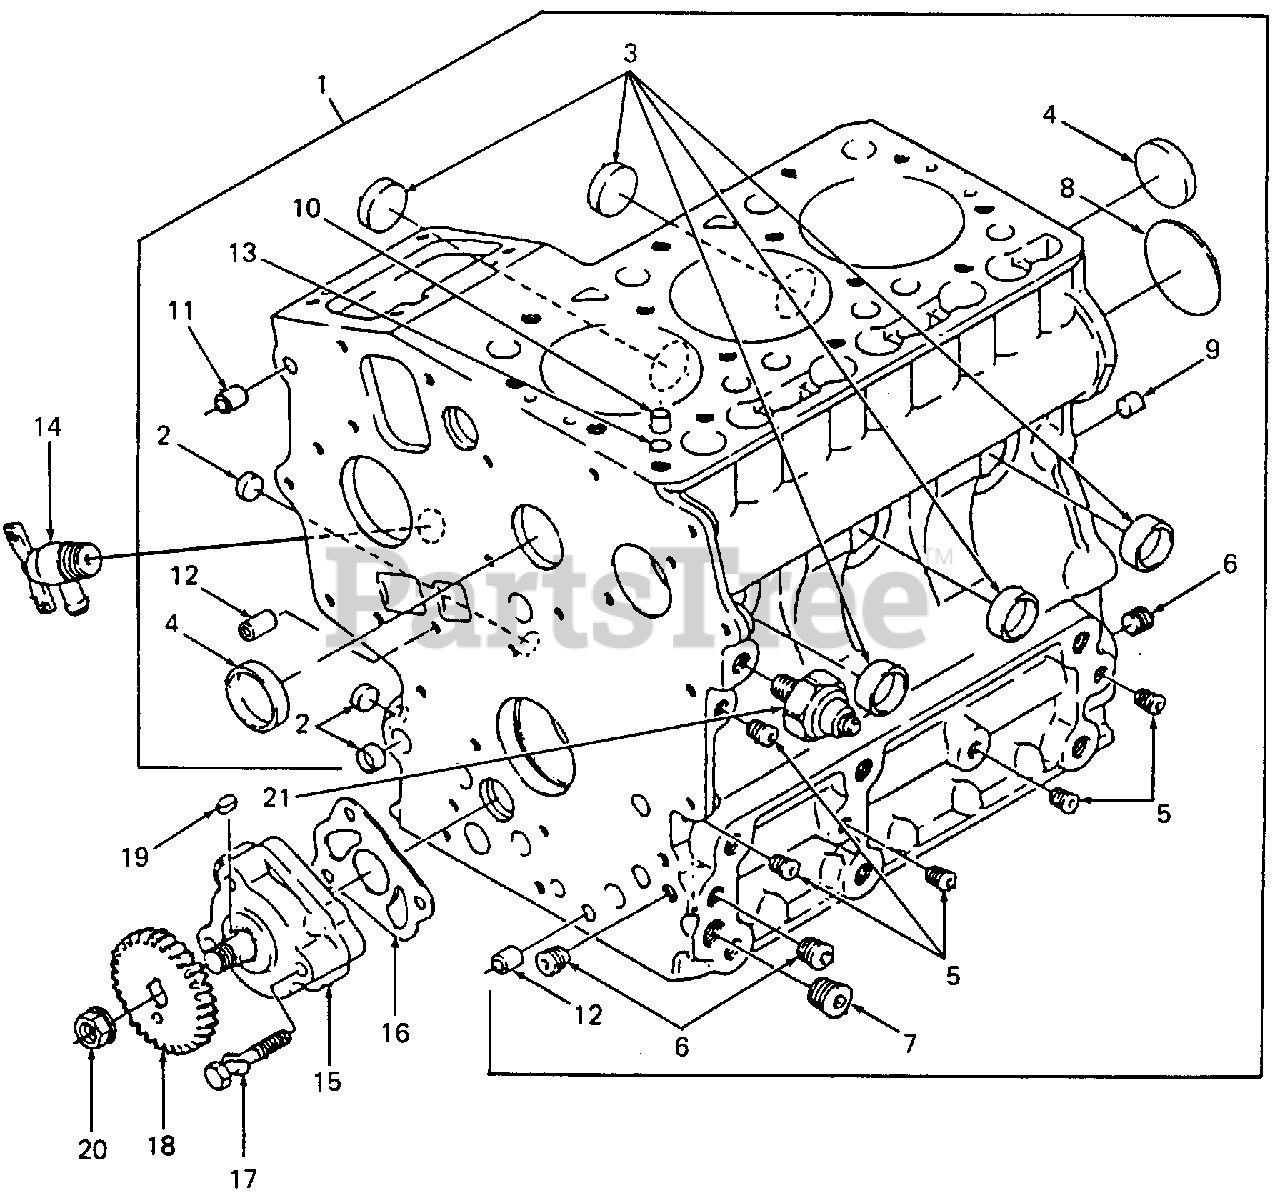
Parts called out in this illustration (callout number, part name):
1	Crankcase Assy
8	Plug, Expansion
9	Pin, Straight
14	Drain Cock Assy
15	Oil Pump Assy
16	Gasket, Oil Pump
18	Gear, Oil Pump Drive
21	Switch, Oil
